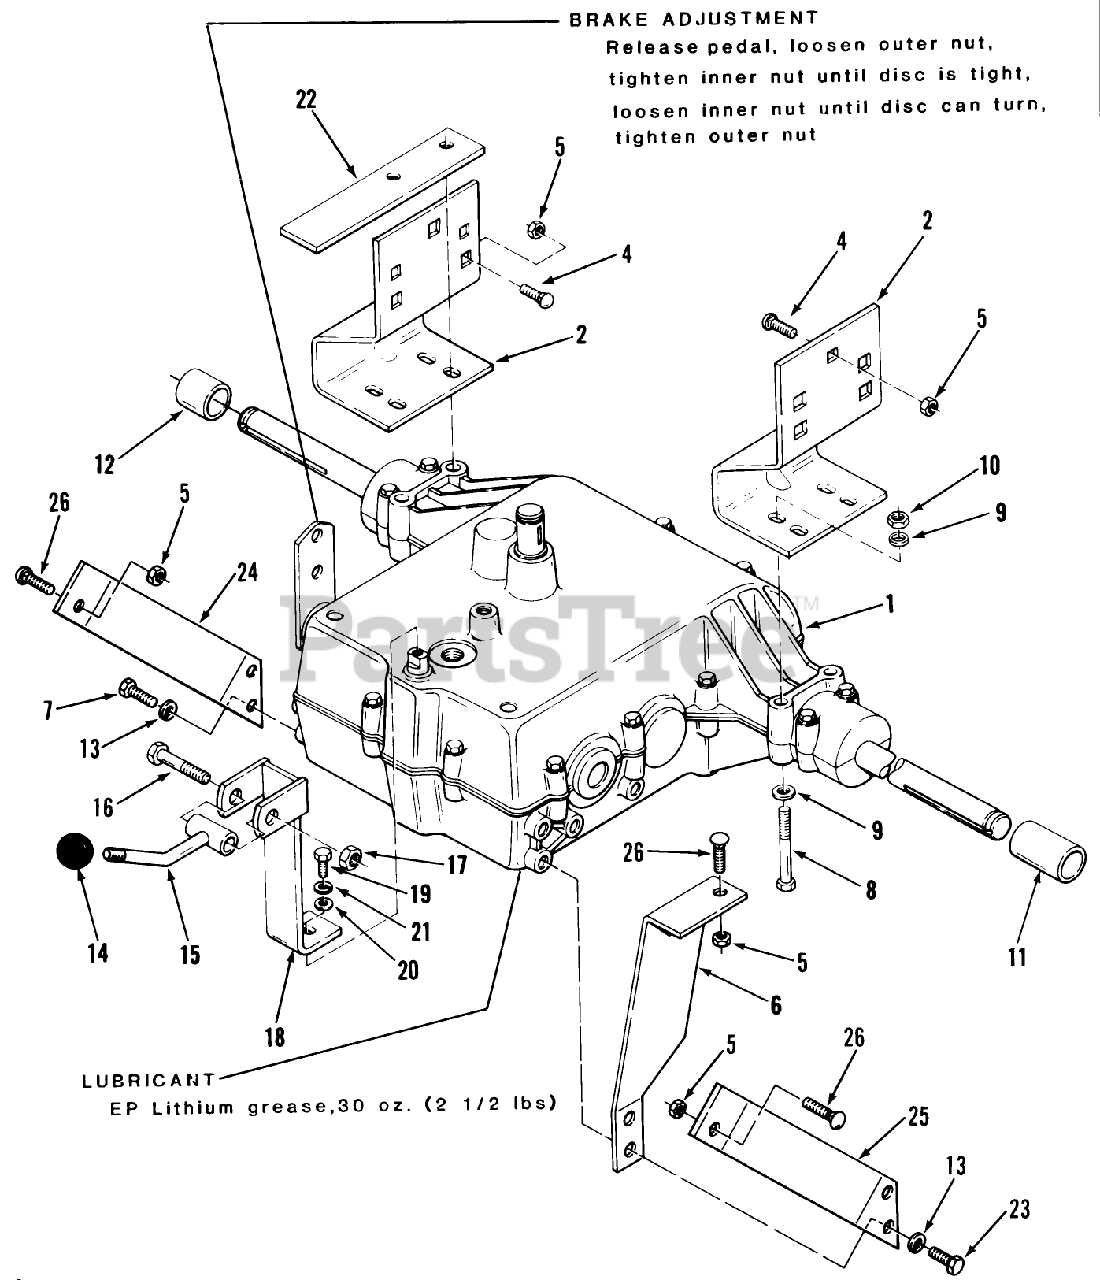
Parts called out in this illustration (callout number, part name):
1	ORDER FROM PEERLESS
4	CARRIAGE BOLT -4
6	TORQUE STRAP
7	Screw
9	WASHER 5/16 SAE
15	ASSY-UPPER SHIFT ROD
18	ASSY LEVER *R
20	WASHER
